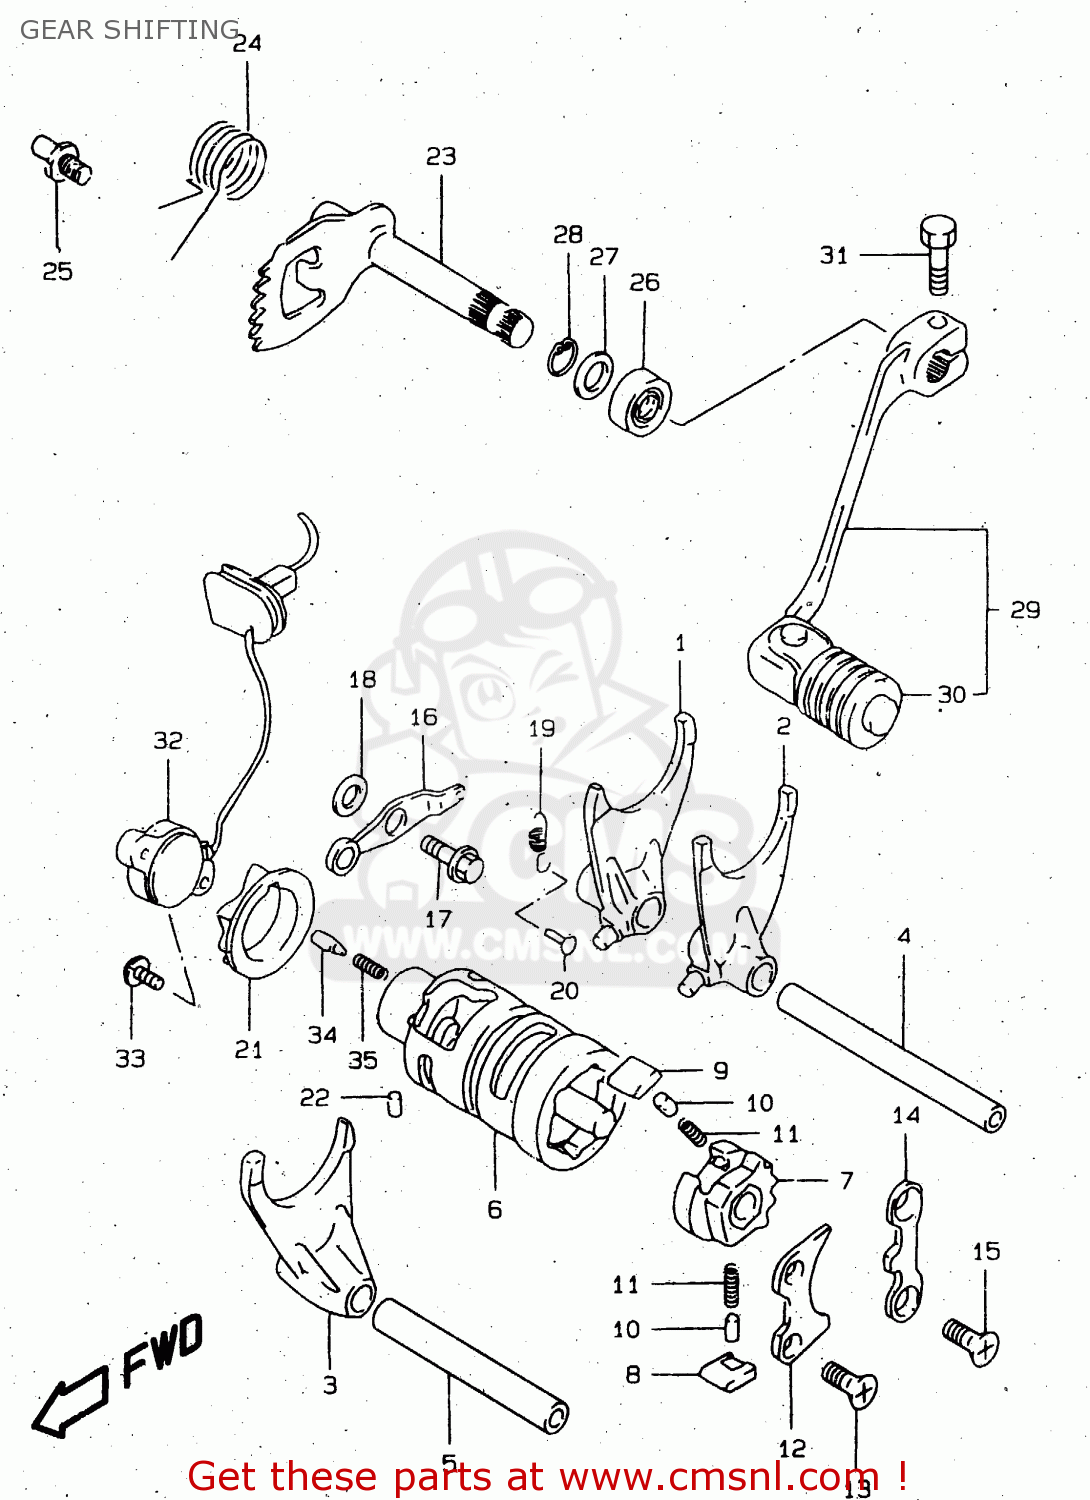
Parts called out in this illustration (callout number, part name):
1	FORK,GEAR SHIFT NO.1
2	FORK,GEAR SHIFT NO.2
3	FORK,GEAR SHIFT NO.3
4	SHAFT,GEAR SHIFT FORK
5	SHAFT,GEAR SHIFT FORK
6	CAM,GEAR SHIFT
7	GEAR,GEAR SHIFT CAM DRIVEN
8	PAWL,GEAR SHIFT NO.1
9	PAWL,GEAR SHIFT NO.2
10	PIN(5X8)
11	SPRING
12	LIFTER,GEAR SHAFT PAWL
13	SCREW
14	STOPPER,GEAR SHIFT POLE
15	SCREW
16	STOPPER,GEAR SHIFT CAM
17	BOLT(6X14.6)
18	WASHER
19	SPRING
20	RIVET
21	PLATE,GEAR SHIFT CAM STOPPER
22	PIN
23	SHAFT,GEAR SHIFT
24	SPRING
25	STOPPER,GEAR SHIFT CAM
26	OIL SEAL
27	WASHER
28	CIRCLIP,12 MM
29	LEVER ASSY,GEAR SHIFT
30	RUBBER,GEAR SHIFT PEDAL
31	BOLT
32	BASE ASSY,GEAR SHIFT TERMINAL
33	SCREW
34	PIN(5X15.5)
35	SPRING
